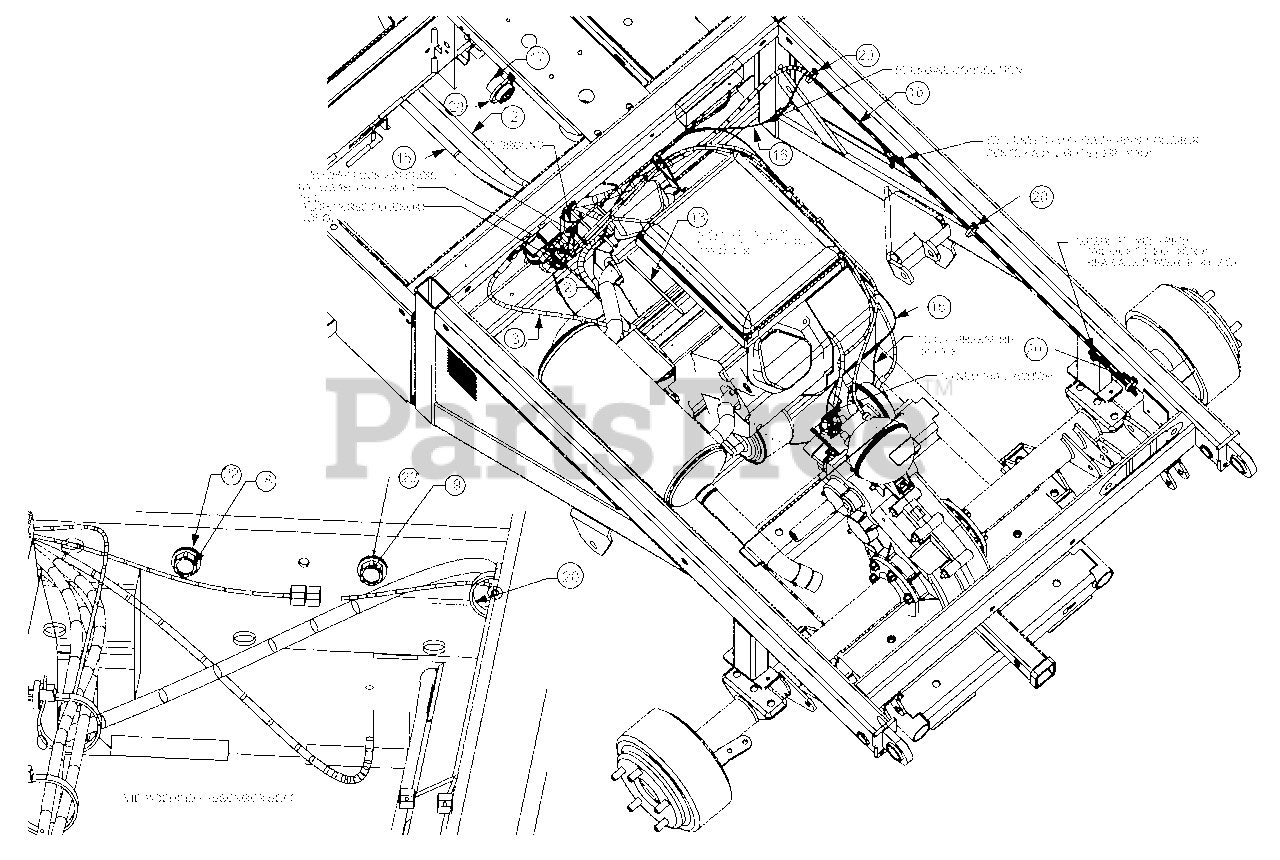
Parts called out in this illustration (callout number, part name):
2	Harness Assembly, Starter
3	Harness Assembly, Motor Ground
6	Screw, Self-tapping, 5/16-18 x .50
8	Screw, Self-tapping, 1/4-20 x 1.000
9	Screw, #10-24 x 0.75
13	Cable Tie, 3/16 x .05 x 7.4
15	Harness, Utility Main
16	Harness, Motor
17	Control, Reverse
20	Cable Tie, .19 x 8.39 Tree Mount
21	Clip .250 Dia.
22	Lock Washer, 1/4
